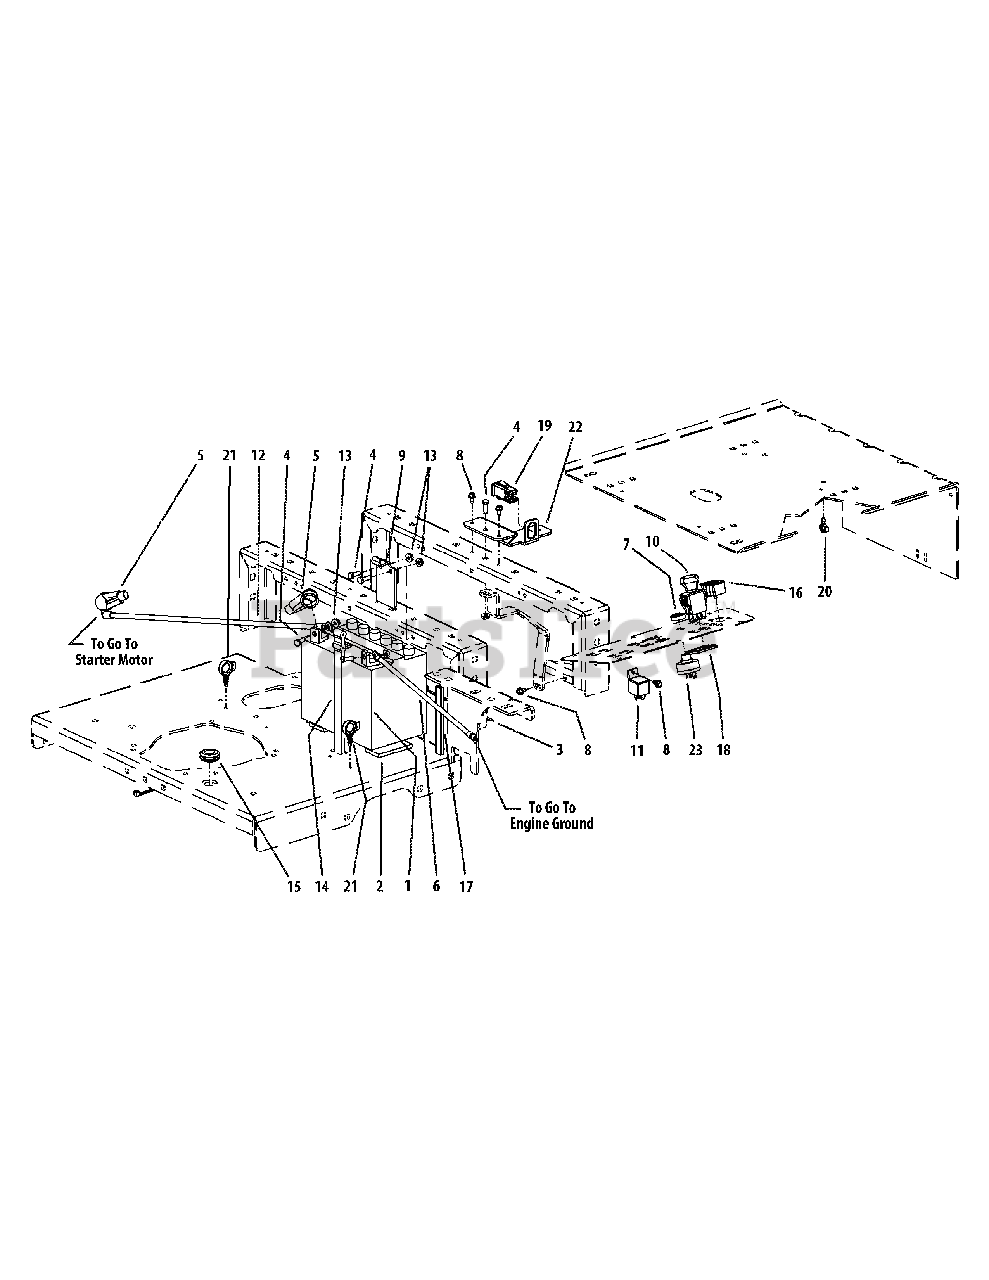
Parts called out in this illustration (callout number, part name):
1	Battery, 12V 225CCA 30 Min
2	Rubber Pad, .25 x 1.50 x 3.00
3	Tie, Cable, 3/16 x .05 x 7.4"
4	Screw, Hex, Cap, 1/4-20 x .75
5	Boot, 1" OD Rubber Battery-PST, Red
6	Cable, Battery, Black, 17"
7	Nut, W/Cap, 5/8-32 Ignition
8	Self Tapping Screw, 1/4-20 x 1/2
10	Switch, Electric, PTO
11	Relay, 12V 40A
12	Cable, Battery, Red, 24"
13	Hex Flange Lock Nut, 1/4-20
14	Strap, Battery
15	Grommet, .75 ID
16	Meter, Hour
17	Battery Edge Trim
18	Bracket, PTO Switch Retainer
19	Switch, Safety N.O./N.C.
20	Electrical Conduit Clip, 3/8
21	Electrical Conduit Clip, 5/8
22	Bracket, Lapbar/Brake Control
23	Switch, Ignition, 6 Pin includes:
